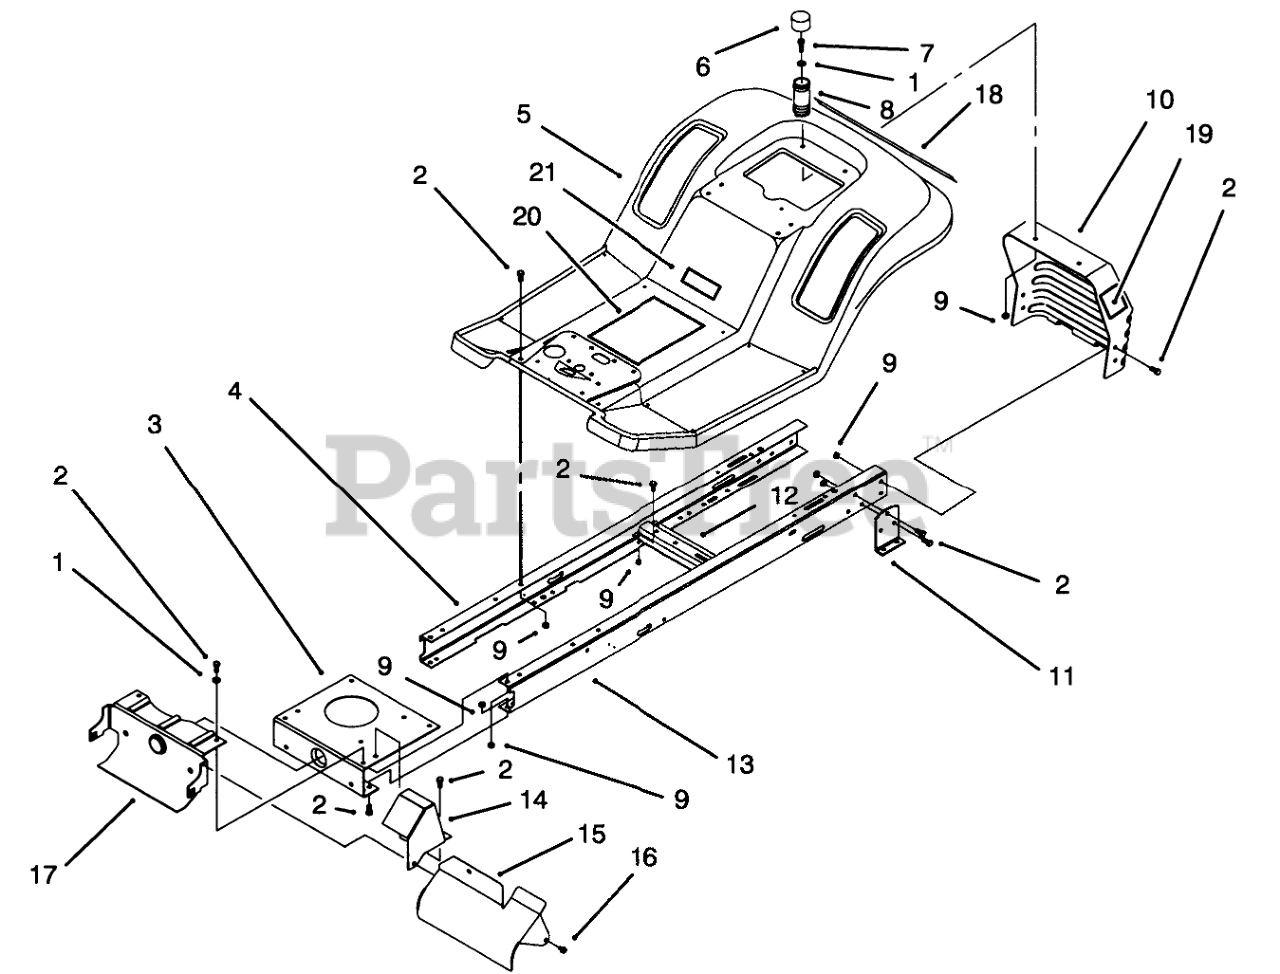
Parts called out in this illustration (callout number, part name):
1	WASHER-PLAIN
2	SCREW-HH
3	Plate-Engine Mount
4	Frame-Rail R.H.
5	BODY-REAR
6	CAP-PROTECTOR
7	SCREW-HH
8	SPRING-COMPRESSION
9	NUT-LOCK, NI
10	Panel-Rear Hitch
11	Bracket-Transaxle
12	Bracket-Idle Pivot
13	Frame-Rail L.H.
14	Shield-Exhaust Pipe
15	Shield-Muffler
16	SCREW-HWHTF
17	Support-FrontAxle
18	DECAL - REAR BODY
19	DECAL - DUMP VALVE
20	Decal-Instruction Hydro
21	Decal-Made In USA
